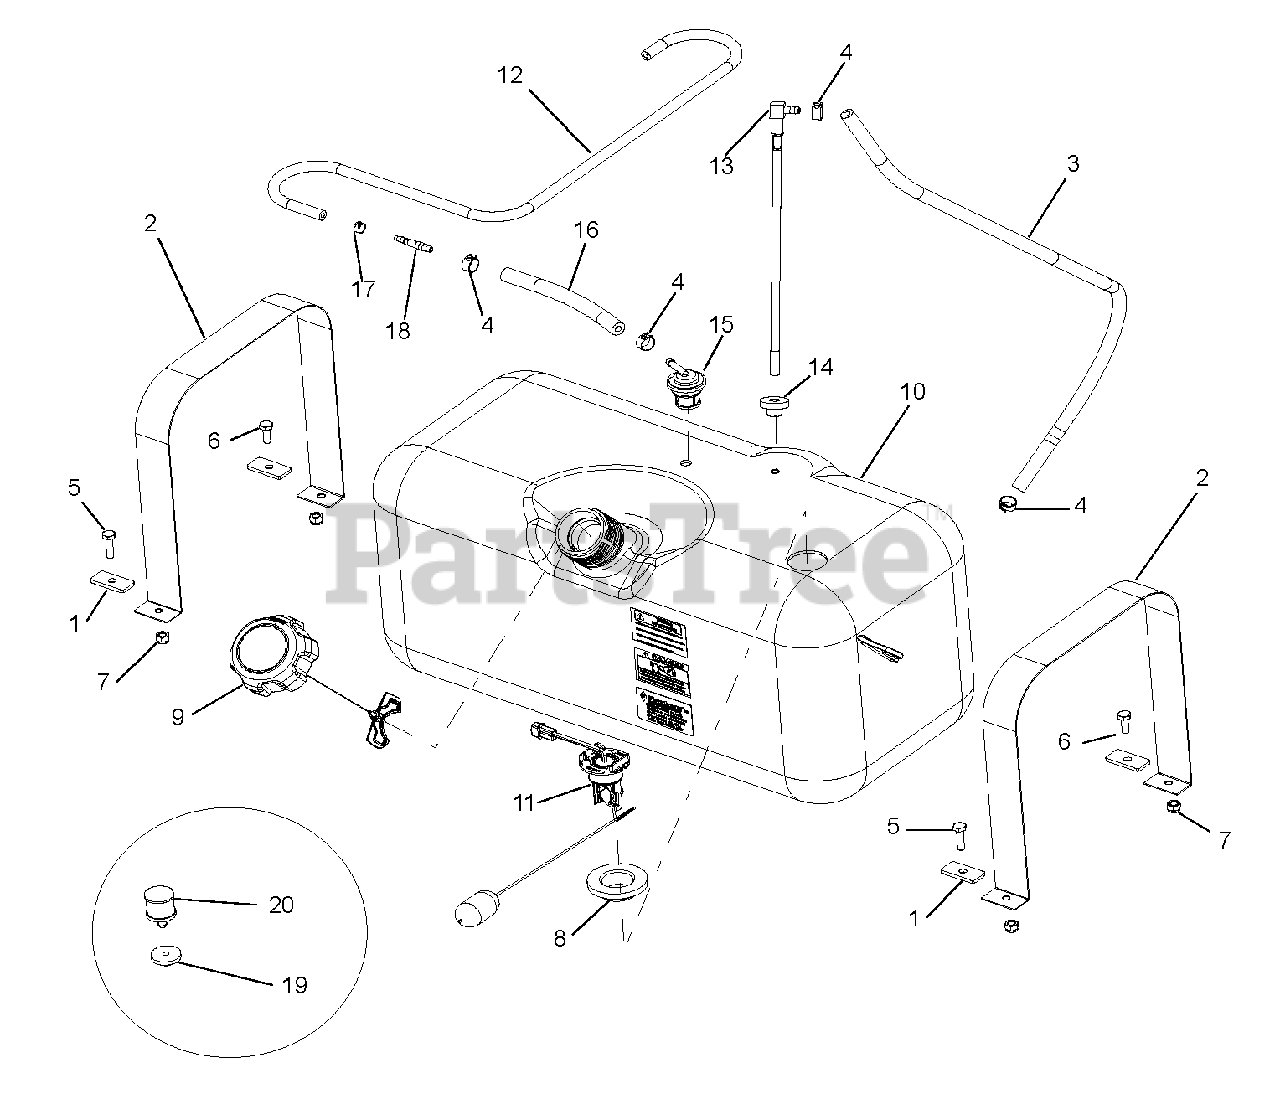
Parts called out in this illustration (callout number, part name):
1	GAS TANK MOUNT SPACER
2	GAS TANK STRAP, WIDE
3	FUEL LINE 10" ST MODEL
4	CLAMP, FUEL LINE, 1/4"
5	BOLT, HEX .25-20 X .75 GR5 YWZC
6	BOLT, HEX .25-20 X 1.00 GR5 YWZC
7	NUT, HEX NYLOCK .25-20 YWZC
8	GROMMET, FUEL SENDER
9	CAP, 2.25" ONE-WAY VENT FUEL
10	FUEL TANK, EPA
11	SENDER, FUEL LEVEL
12	HOSE, .188 LOW PERM 34"
13	FUEL, TANK PICK-UP LINE
14	GROMMET, DAPCO VITON #12240
15	IN-LINE CHECK VALVE, GROMMET FUEL TANK VENT (SN 20,000 +)
16	HOSE, .25 LOW-PERM BULK GAS, 6" (SN 20,000 +)
17	CLAMP, FUEL LINE, 3/16"
18	ADAPTOR, HOSE 3/16" TO 1/4" (SN 20,000 +)
19	GROMMET, FUEL TANK (SN 10,000 – 19,999)
20	SLOSH VALVE, FLAMBEAU 468885A (SN 10,000 – 19,999)
